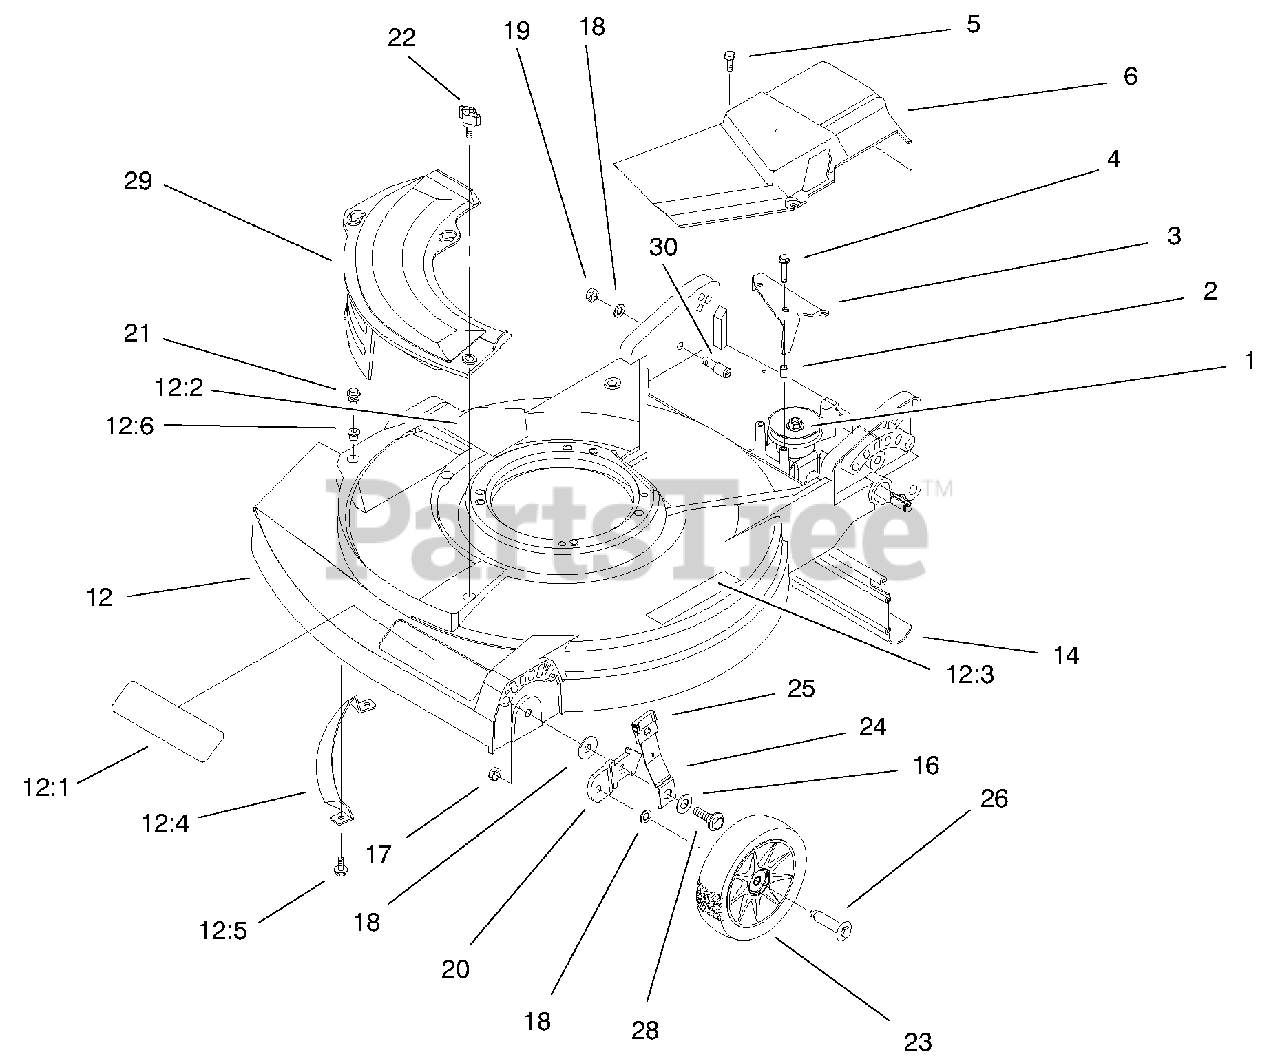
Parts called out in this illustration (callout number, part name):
1	ASM-Gear Case
2	Bushing-Spacer
3	Bracket-Actuator
4	Screw
5	Screw-Thread Forming
6	Cover-Drive
12:1	Decal-Deck
12:2	Decal-Danger
12:3	Decal-Warning
12:4	Toe Bar 21
12:5	Screw-HWH
12:6	Grommet-Plastic
14	Shield-Trailing
16	Washer-Spring
17	Nut-Lock
19	Nut-Lock
20	Bracket-Wheel Height Adj
21	Screw-Sems
22	Knob-Cover Plate
23	ASM-Wheel & Tire 6"
24	ASM-Spring Arm
25	Knob-Height Adjust
26	Bolt-Shoulder
28	Bolt-Shoulder
29	Mulch Plate-21"
30	Bolt-Shoulder
